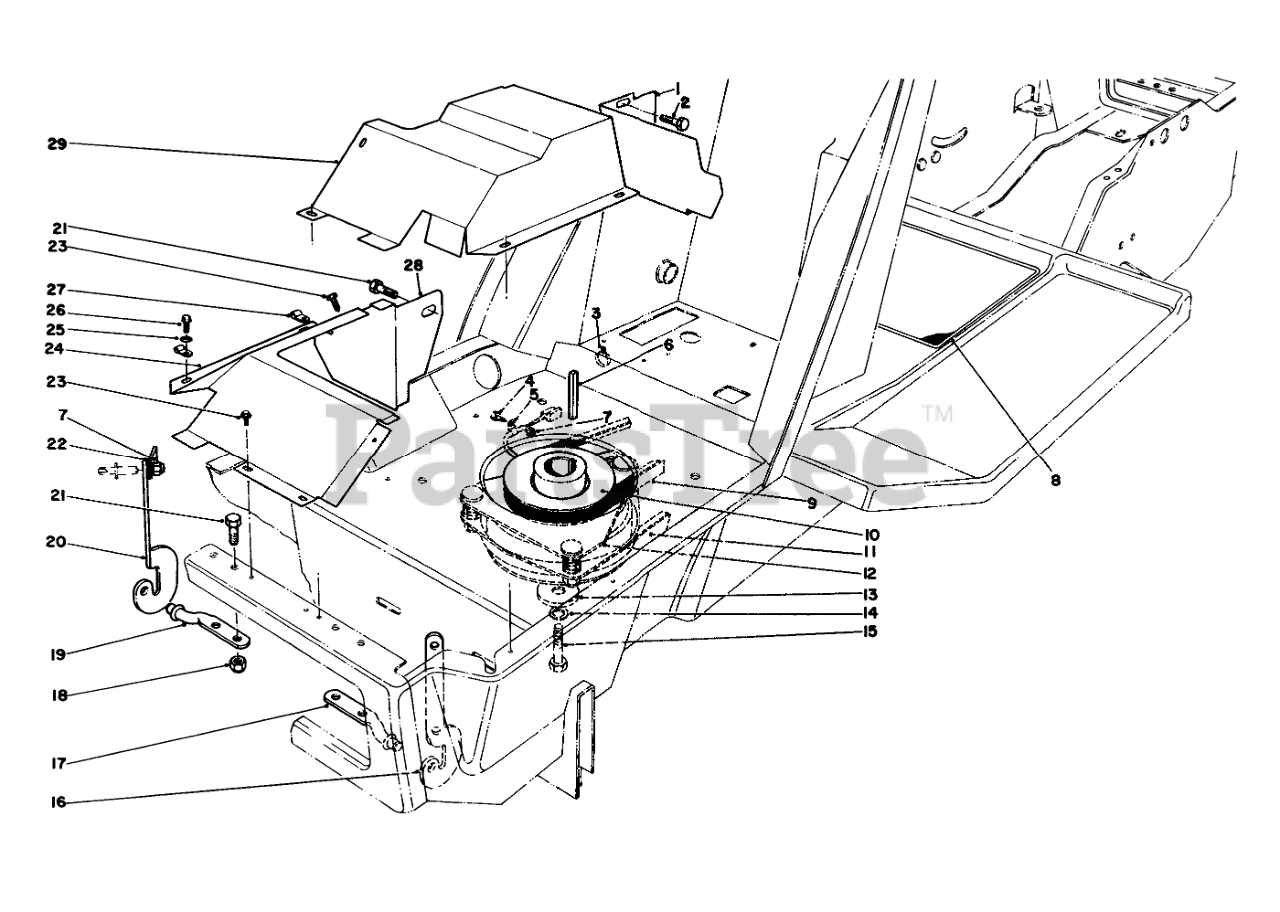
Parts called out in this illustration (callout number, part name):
1	EXH SHIELD SUPT B
2	SCREW-HH
3	TIE-MOUNT, PUSH
4	SCREW-HH
5	CLAMP
6	KEY-SQUARE
7	NUT-LOCK, NI
8	OPERATION DECAL
9	V BELT
10	Pulley
11	V-BELT
12	Clutch Assembly-Deck
13	WASHER-CLUTCH
14	WASHER-LOCK
15	SCREW-HH
16	L.H. HINGE BRACKET
17	LH HOOD HINGE PIN
18	NUT-LOCK, CONE
19	RH HOOD HINGE PIN
20	RH HINGE BRKT
21	SCREW-HH
22	SCREEN SUPT BRKT
23	SCREW-HWHTF
24	Heat Shield
25	WASHER-FLAT
26	SCREW
27	CABLE CLAMP
28	Support Heat Shield
29	HEAT SHIELD WA B
